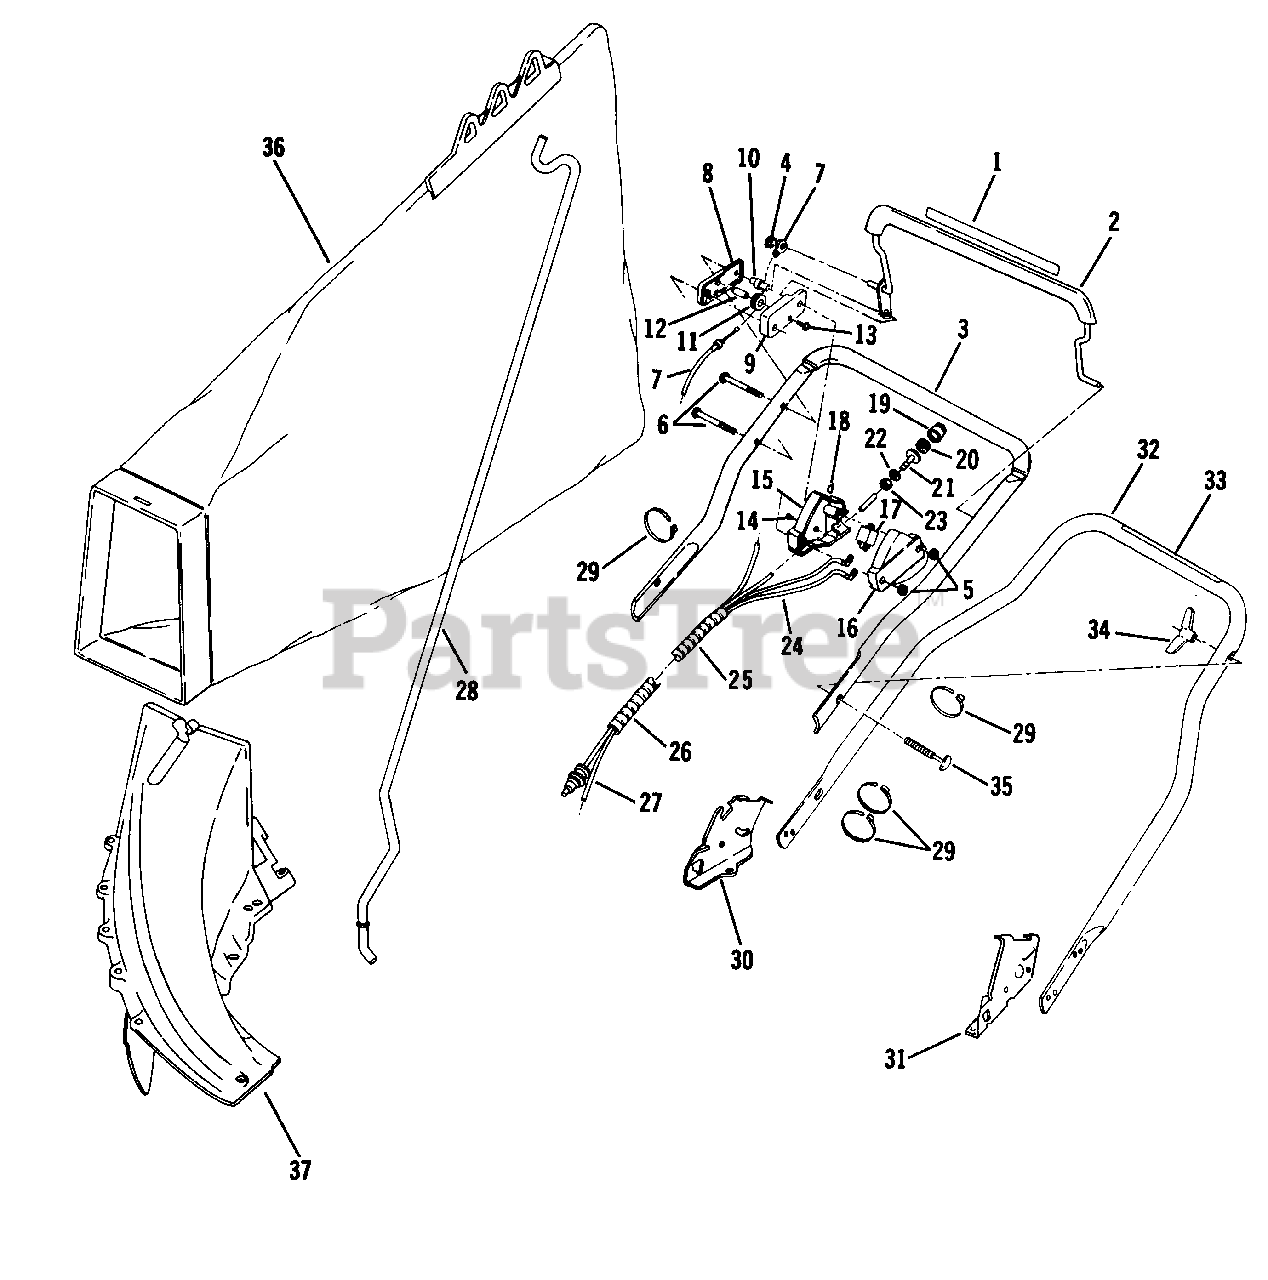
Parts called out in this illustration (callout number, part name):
1	Decal-Blade Control
2	Control Lever Assembly
3	Top Handle and Grip Assembly
4	Pushnut
5	Nut-Hex-Centerlock
6	Screw
7	Control Cable Assembly
8	Control Case-Outer
9	Control Case-Inner
10	Column
11	Pulley
12	Pin
13	Screw
14	Screw
15	Console-R.H.
16	Console-L.H.
17	Switch Assembly
18	Decal
19	Primer Bulb
20	Filter
21	Primer Base
22	Washer
23	Locknut
24	Wire Harness Assembly
25	Spiral Tubing
26	Spiral Tubing
27	Tubing
28	Rod-Grass Bag
29	Tie Strap
30	Handle Bracket-R.H.
31	Handle Bracket-L.H.
32	Handle-Bottom
33	Decal-Starting Inst.
34	Knob
35	Screw-Folding Handle
36	Bag Assembly
37	Chute Assembly
